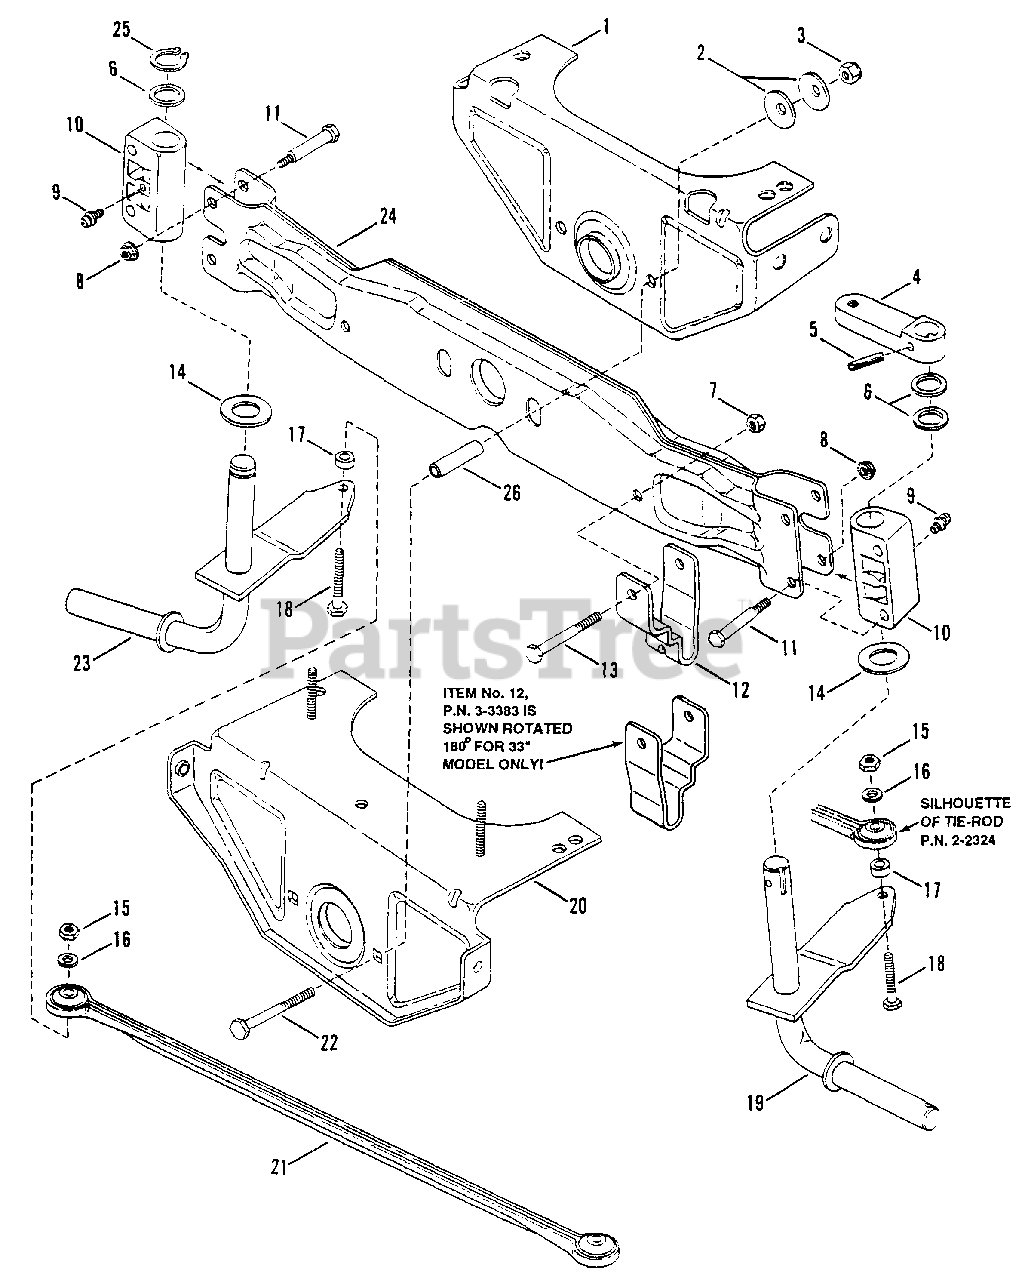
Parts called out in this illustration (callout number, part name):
1	BRACKET, Axle (Rear)
2	WASHER, Cone
3	NUT, 3/8-16 Nyloc
4	ARM, Steering
5	ROLL-PIN, 1/4 x 1 1/4"
6	WASHER, Shim
7	NUT, 5/16-18 Center Lock
8	NUT, 1/4-20 Hex Flange Top-Lock
9	LUBE FITTING, Straight (press-fit for .187 dia. Hole)
10	BEARING, Spindle
11	BOLT, 1/4-20 x 1 41/64" Shoulder
12	BRACKET, Deck Hanger
13	SCREW, 5/16-18 x 2 1/2" Hex Head Cap
14	WASHER, Thrust
15	NUT, 3/8-16 Hex
16	WASHER, 3/8 Split Lock
17	SPACER, Tie-Rod
18	SCREW, 3/8-16 x 1 1/2" Hex Head Cap, Grade 5
19	SPINDLE ASSEMBLY, Left Hand, Long
19	SPINDLE ASSEMBLY, Left Hand, Short
20	BRACKET ASSEMBLY, Axle (Front)
21	TIE-ROD
22	BOLT, 3/8-16 x 3" Hex Head
23	SPINDLE ASSEMBLY, Right Hand, Long
23	SPINDLE ASSEMBLY, Right Hand, Short
24	AXLE, Front
25	RING, Retaining
26	SPACER
